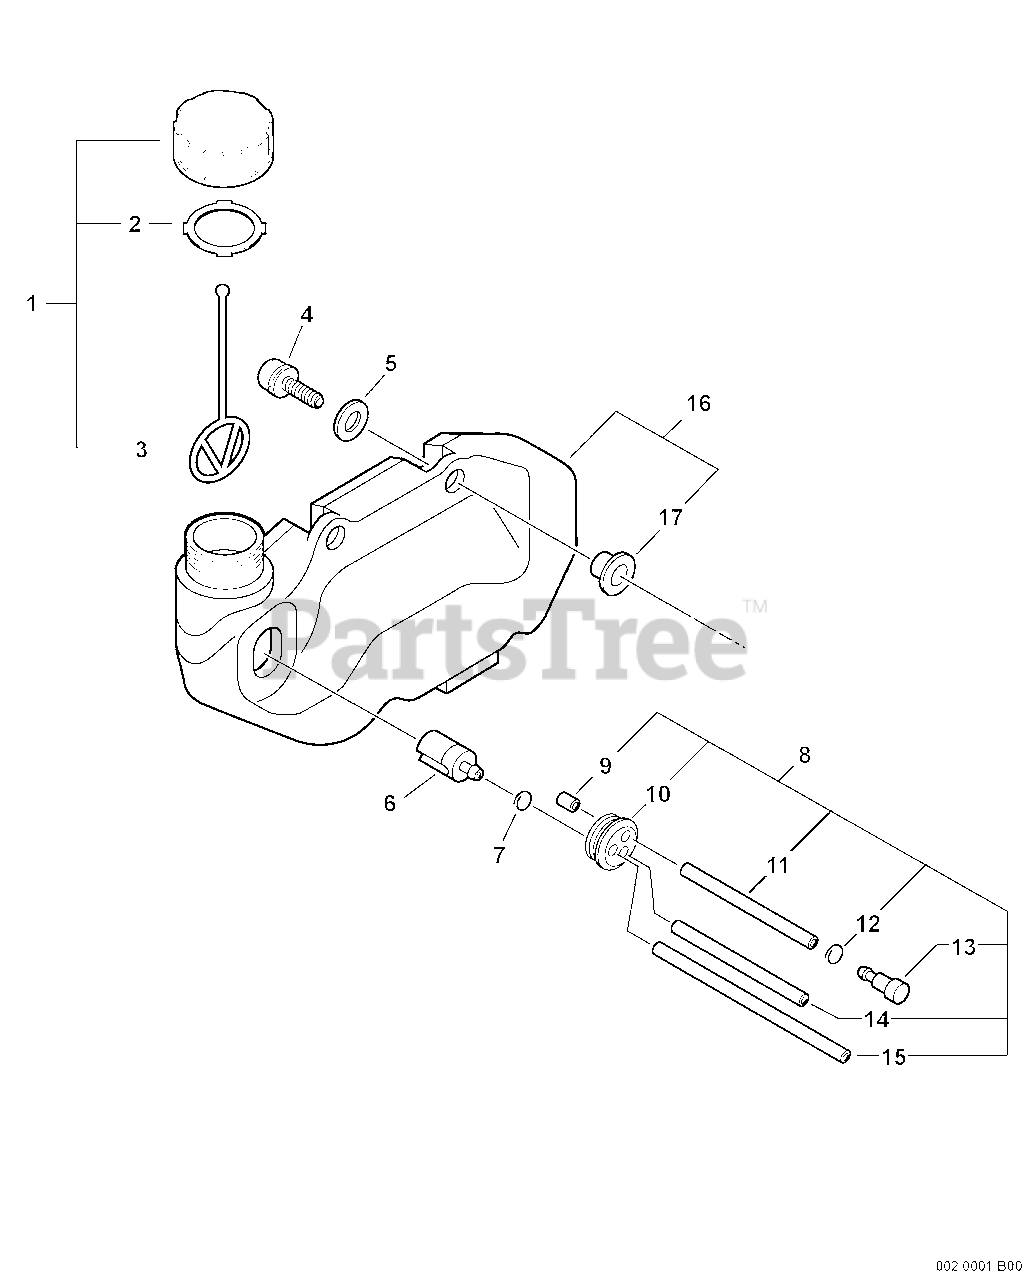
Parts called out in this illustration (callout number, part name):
1	CAP ASSY - ORANGE
2	GASKET, CAP
3	CONNECTOR, CAP
4	SCREW - 5X18
5	WASHER - 5
6	FILTER, FUEL
7	CLIP - 6
8	FUEL PIPE KIT
9	COLLAR - 3
11	PIPE - 3X5X65 -- BLACK
12	CLIP - 5.5
13	VENT, FUEL TANK
14	PIPE - 3X5X170 -- CLEAR
15	PIPE - 3X5X275 -- BLACK
16	TANK, FUEL
